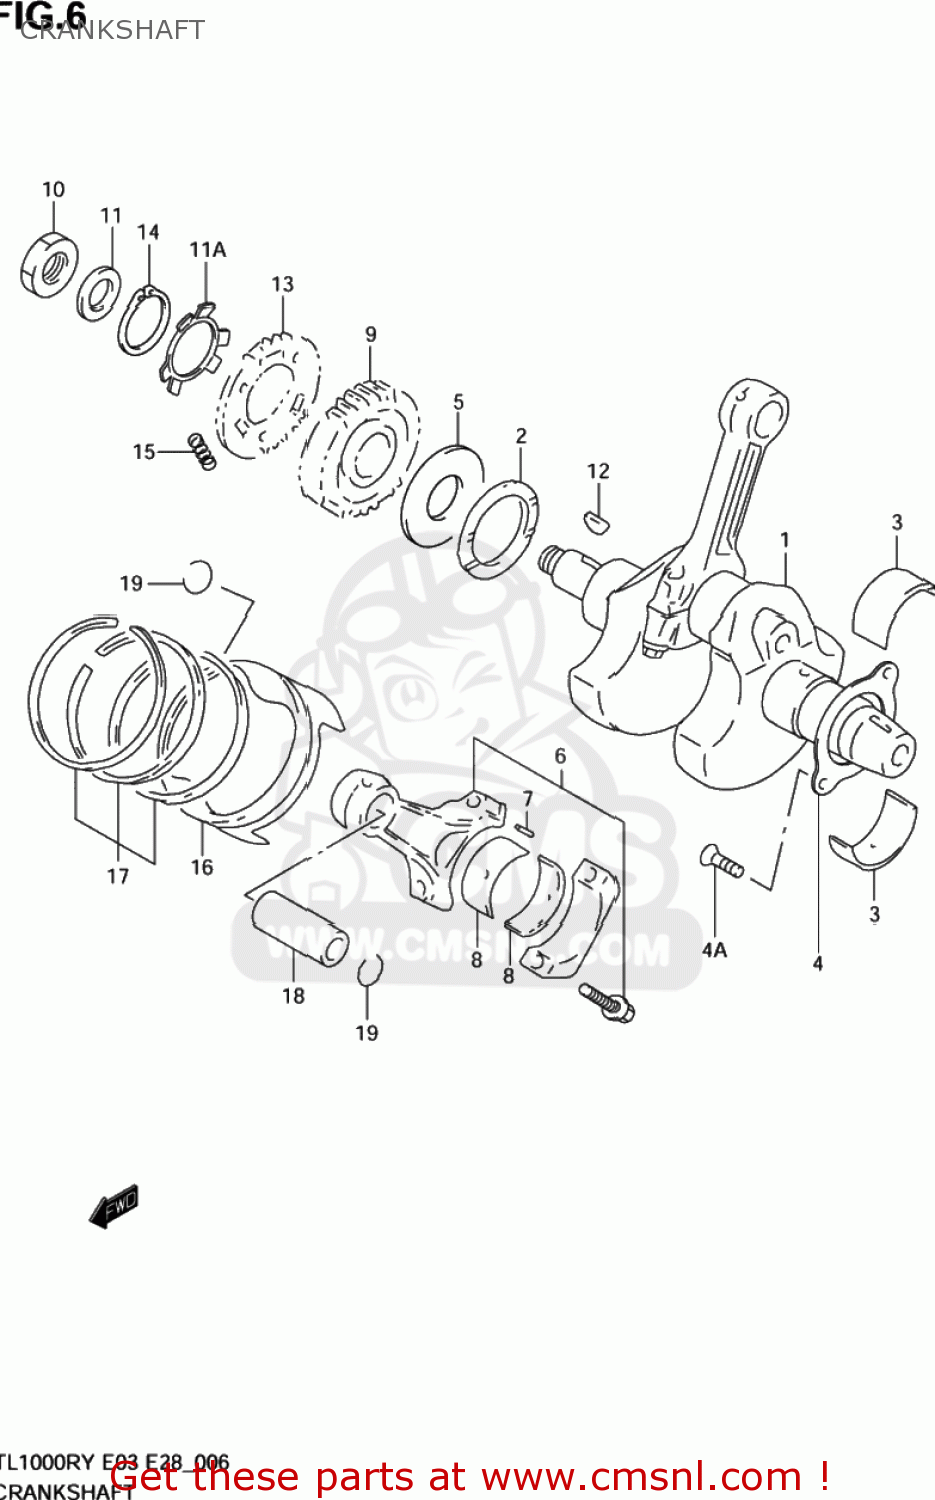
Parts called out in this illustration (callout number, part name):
1	CRANKSHAFT SET
2	WASHER(48.1X64X1.94)
3	BEARING,CRANKSHAFT
4	RETAINER,CRANKSHAFT BAG,L
4A	SCREW(6X12)
5	WASHER,CRANK THRUST
6	CONNECTING ROD ASSY
7	PIN,CONNECTING ROD
8	BEARING,CRANK PIN
9	GEAR,PRIMARY DRIVE
10	NUT
11	WASHER
11A	WASHER,PRI DRIVE
12	KEY
13	GEAR,PRIMARY DRIVE SCISSORS
14	CIRCLIP
15	SPRING
16	PISTON
17	RING SET,PISTON
18	PIN,PISTON
19	CIRCLIP
